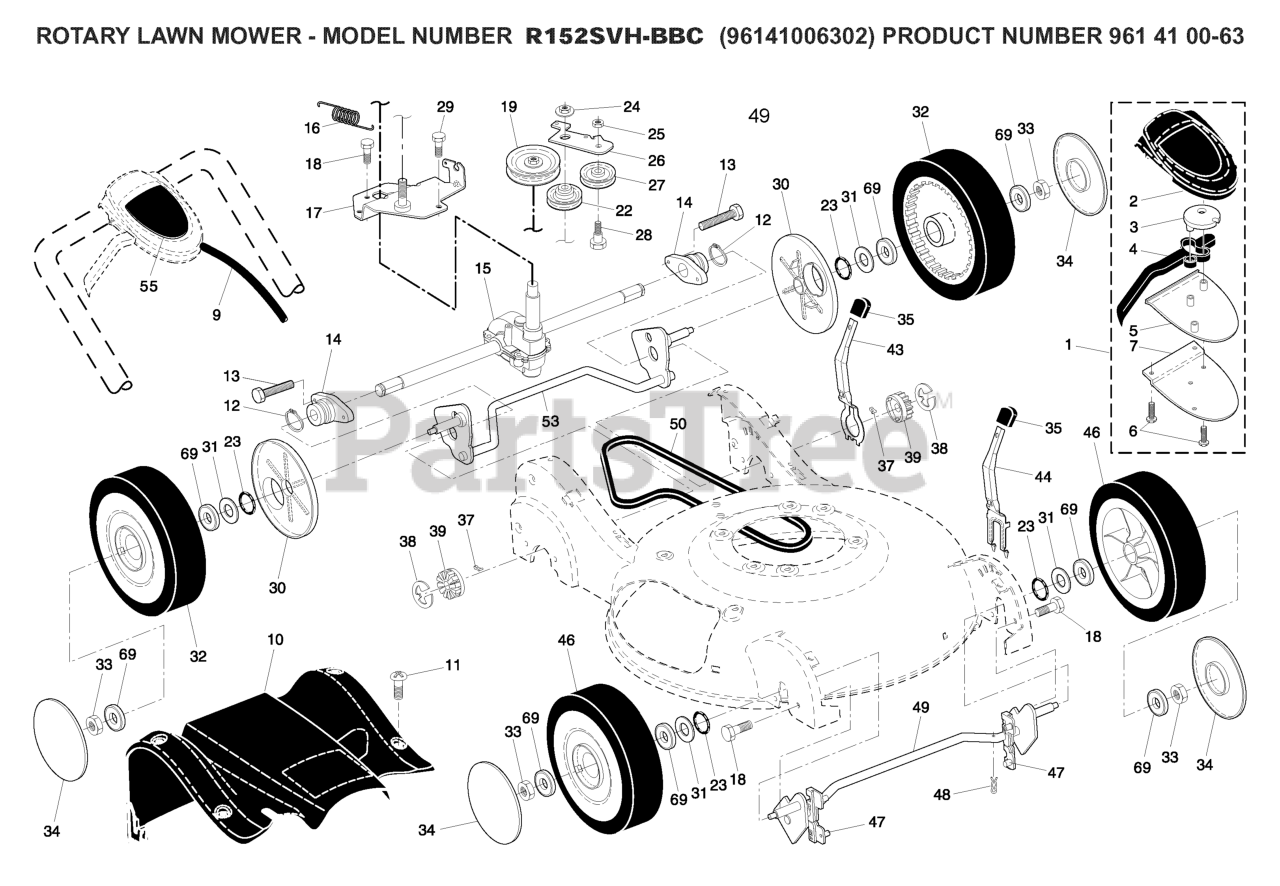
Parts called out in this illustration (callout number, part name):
1	CONTROL.DR.HV.RWGD.GRY/BLU
2	COVER TOP AUTO WALK CONTROL
3	PULLEY.CAM.DRIVE.CONTROL.HV
4	LEVER
5	COVER BOTTOM AUTO WLK CONTROL
6	SCREW, PHILLIPS HEAD 10 X 5/8
7	BRACKET.DRIVE.CONTROL.MOUNT.BL
9	ASM.CABLE.
10	COVER.DRIVE.REAR.21.HV.GRAY
12	RETAINING RING (2 2)(3 2)
13	HINGE SCREW
14	BEARING / AXLE SUPPORT
15	TRANSMISSION.21.RWGD.HV
17	BRACKET, GEAR CASE / DRIVE
19	RP PULLEY.DRIVE.EZ
22	PULLEY.IDLER.V-BELT
23	O-RING..070X.487.NEOPRENE
24	NUT.HEX.FLANGE.3/8-16.LOCKNUT
25	NUT.CENTERLOCK.5/16-
27	IDLER PULLEY
28	SHOULDER BOLT
29	SCREW 14-20 X 5/8
30	DUST COVER, WHEEL
31	WASHER.FLAT.1/2
32	WHEEL.9X2.25.PR.JUNG.BLK
33	NUT.HEX.FLANGE.3/8-16.LO(3 2)
34	HUBCAP.WHEEL.5.SPOKE.SILVER
35	KNOB.SELECTOR.SPRG.H-GRY (2 2)
37	PAWL, DRIVE
38	E-RING 7/16 RE
39	PINION.14.TEETH.FGD
43	LEVER, SELECTOR, HEIGHT, REAR
44	LEVER, SELECTOR, HEIGHT, FRONT
46	WHEEL.9X2.25.LP.JUNG.BLACK
47	BUSHING.FRONT.TORQUE.SHAFT
48	SPRING RETAINER
49	SHAFT FRONT
50	BELT, DRIVE
53	SHAFT.ASM.REAR.TORQUE.HV.BZP
55	DECAL, DRIVE
69	BEARING.8".WHEEL
